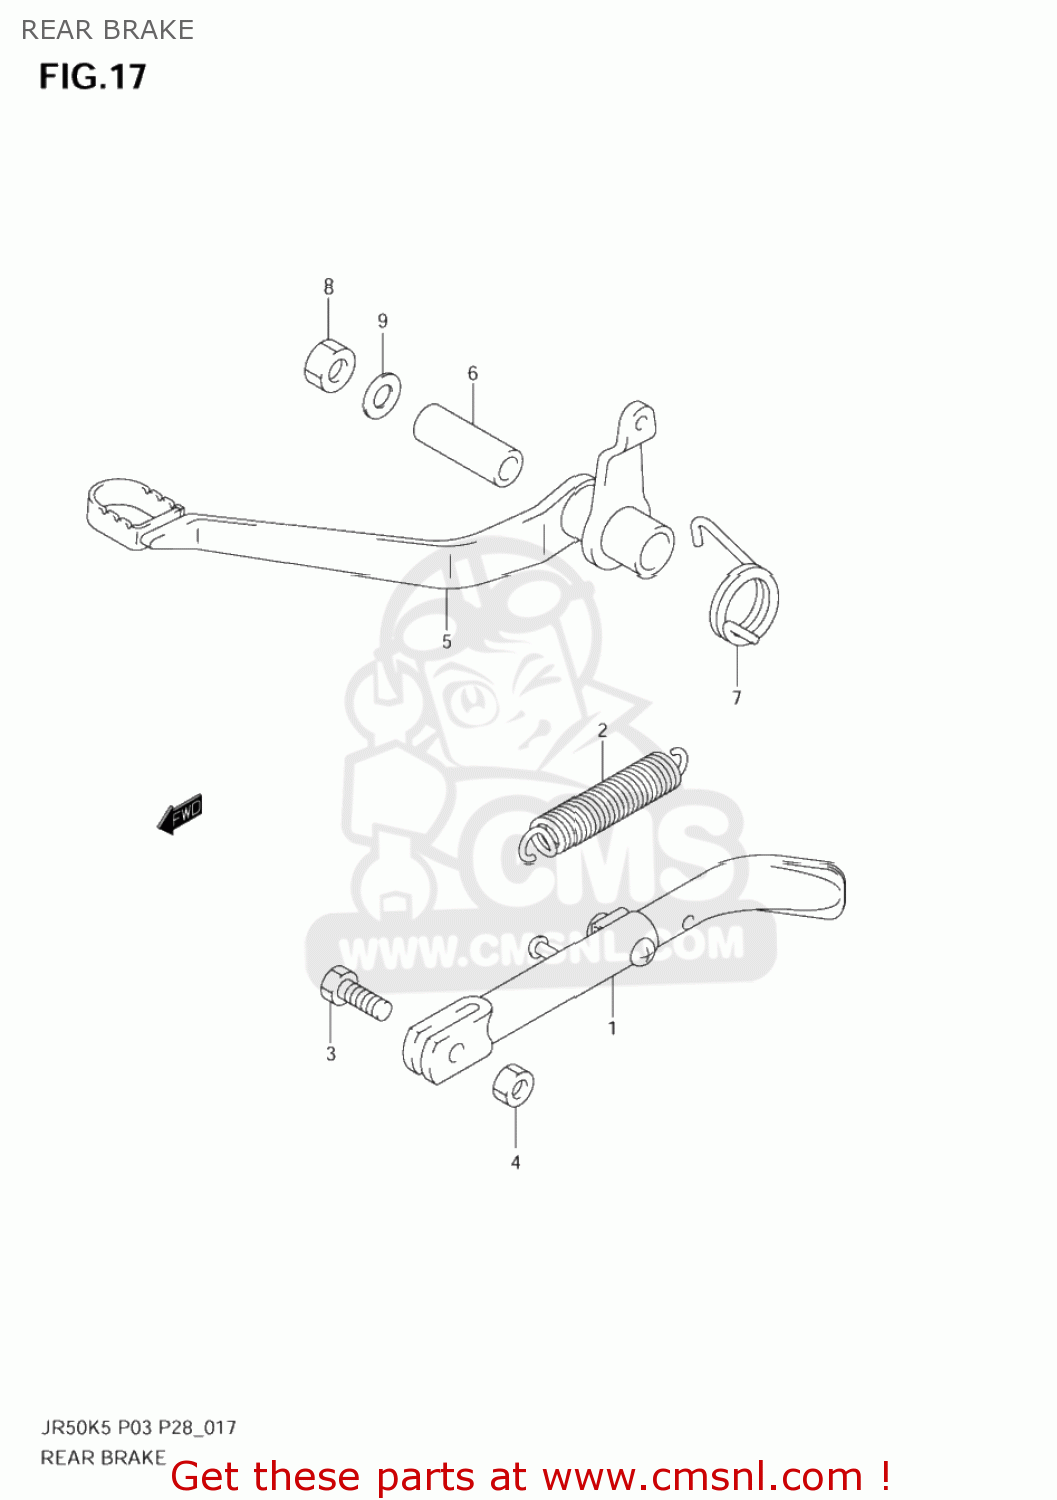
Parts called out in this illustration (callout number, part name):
1	STAND,PROP
2	SPRING
3	BOLT(8X22)
4	NUT
5	PEDAL,BRAKE
6	SPACER,BRAKE PEDAL
7	SPRING,BRAKE PEDAL RETURN
8	NUT
9	WASHER(10.5X22X1.6)
